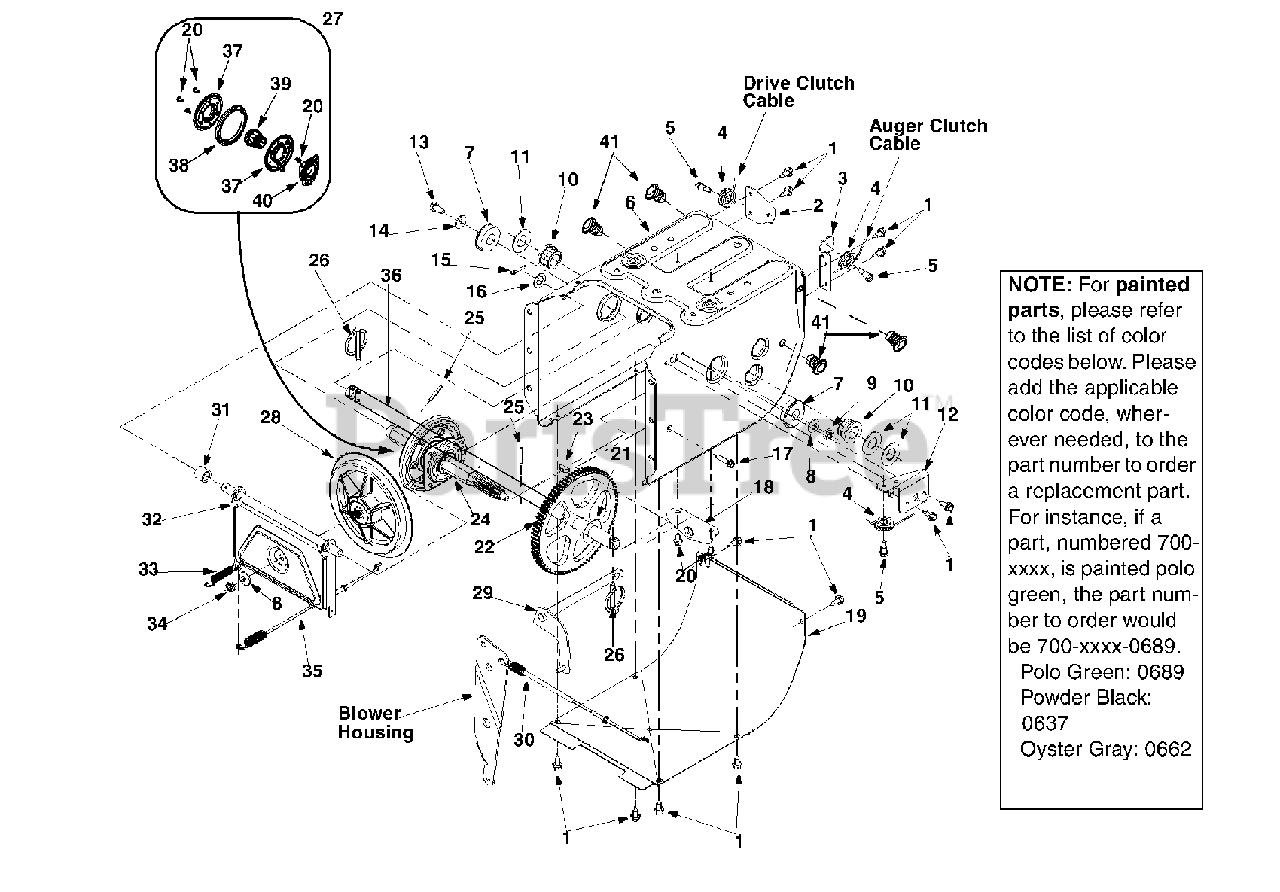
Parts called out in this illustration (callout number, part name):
1	Hex Screw
5	Hex Screw 1/4-28
8	Bell Washer
9	Lock Jam Nut
10	Hex Flange Bearing
11	Flat Washer
14	Bell Washer .340 ID x .872 OD
15	Cotter Pin
16	Flat Washer .536 ID x .930 OD
17	Hex Washer Screw 1/4-20
21	Flat Washer .760 ID x .50 OD
24	7-Tooth Shaft
25	Roll Pin
26	Klik Pin
27	Friction Wheel Assembly
28	Friction Disc Wheel
29	Wheel Shift Rod Assembly
30	Auger Cable
31	Spacer
34	Jam Nut 3/8-24
35	Drive Cable
36	Axle 13" Wheels
37	Friction Plate
38	Friction Wheel Rubber
39	Friction Wheel Hub
40	Friction Wheel Bearing
41	Nut Insert
